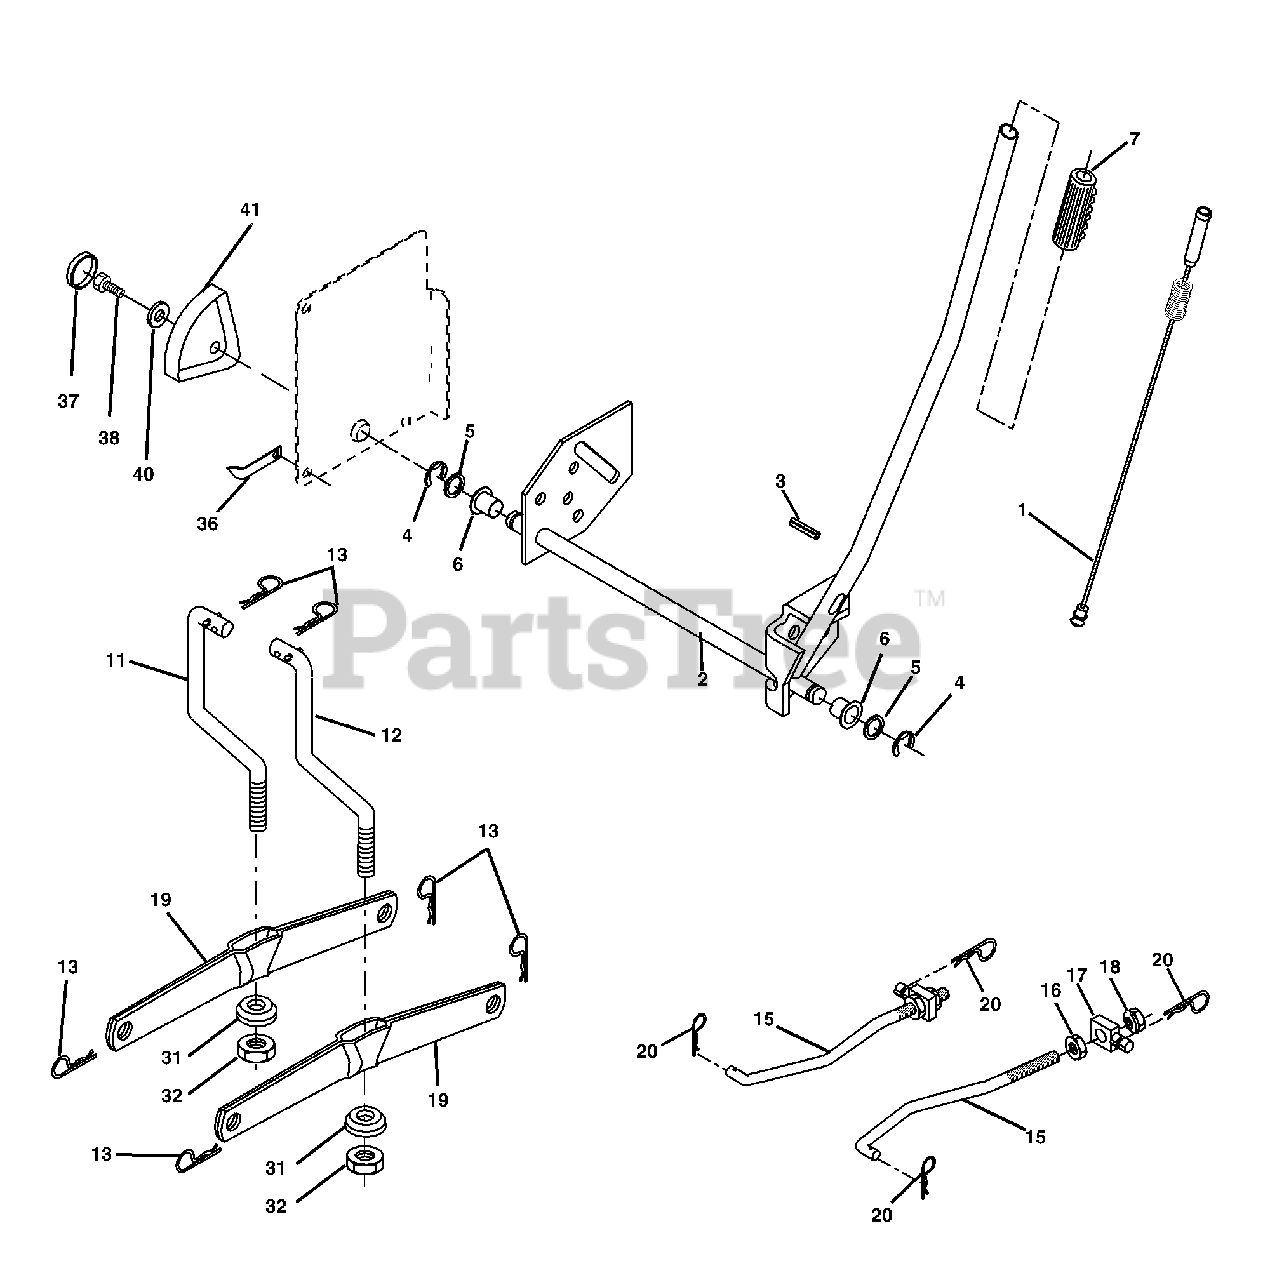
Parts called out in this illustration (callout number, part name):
1	Plunger Assembly
2	Shaft Assembly, Lift
3	Pin, Groove
5	Washer 21/32 x 1 x 21 Ga.
6	Bearing, Nylon
7	Grip, Handle, Fluted
11	Link, Lift, L.H.
12	Link, Lift, R.H.
13	Retainer Spring
15	Link Front Sus.
16	Nut Hex Jam 1/2-13 unc
17	Trunnion Front Susp.
18	Nut Lock w/Wsh 1/2-13 unc
19	Arm Asm. Suspension Mower
20	Retainer Spring
31	Bearing Pivot Lift
32	Nut Crownlock 3/8-24
36	Pointer Height Indicator
37	Plug Hole
38	Screw 5/16-18 x 1
40	Washer 11/32 x 1-1/2 x 10 Ga.
41	Indicator Height Stlt
